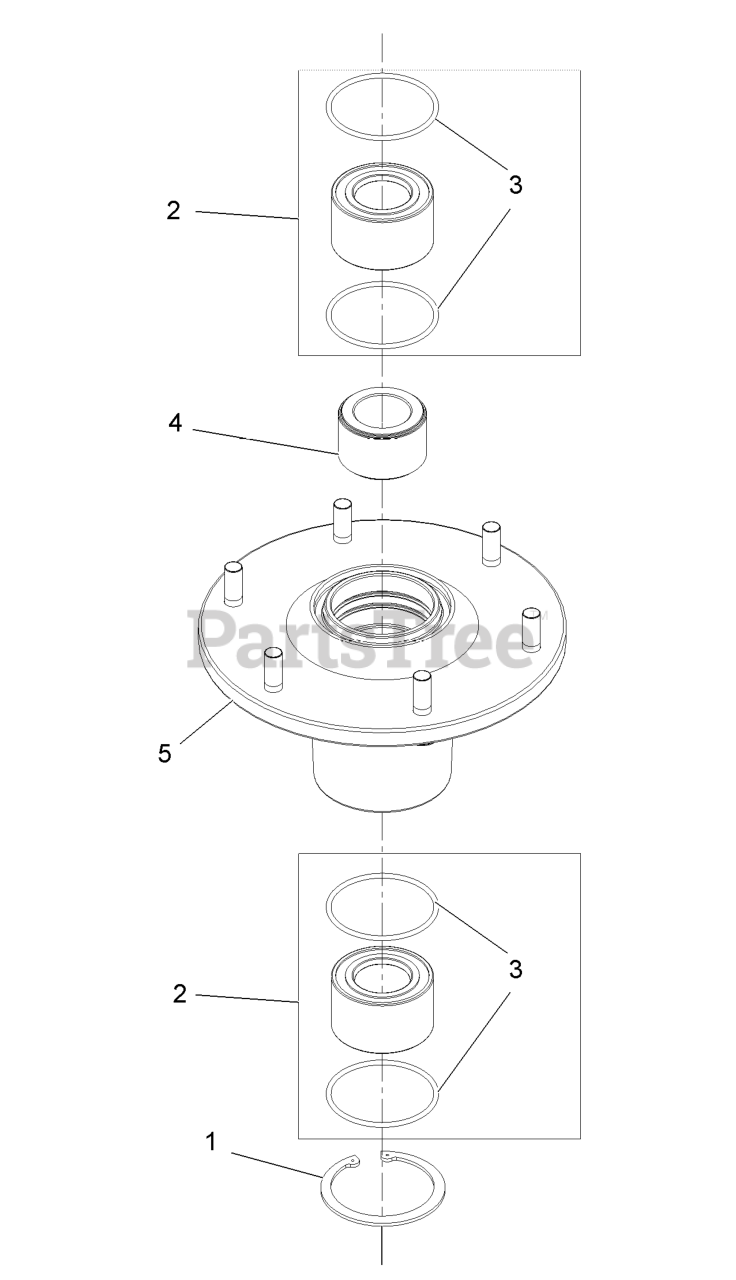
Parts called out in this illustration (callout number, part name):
1	RING-RETAINING
2	ASM, BEARING W/ORINGS
4	SPACER,BEARING
5	ASM,HOUSING W/STUDS
